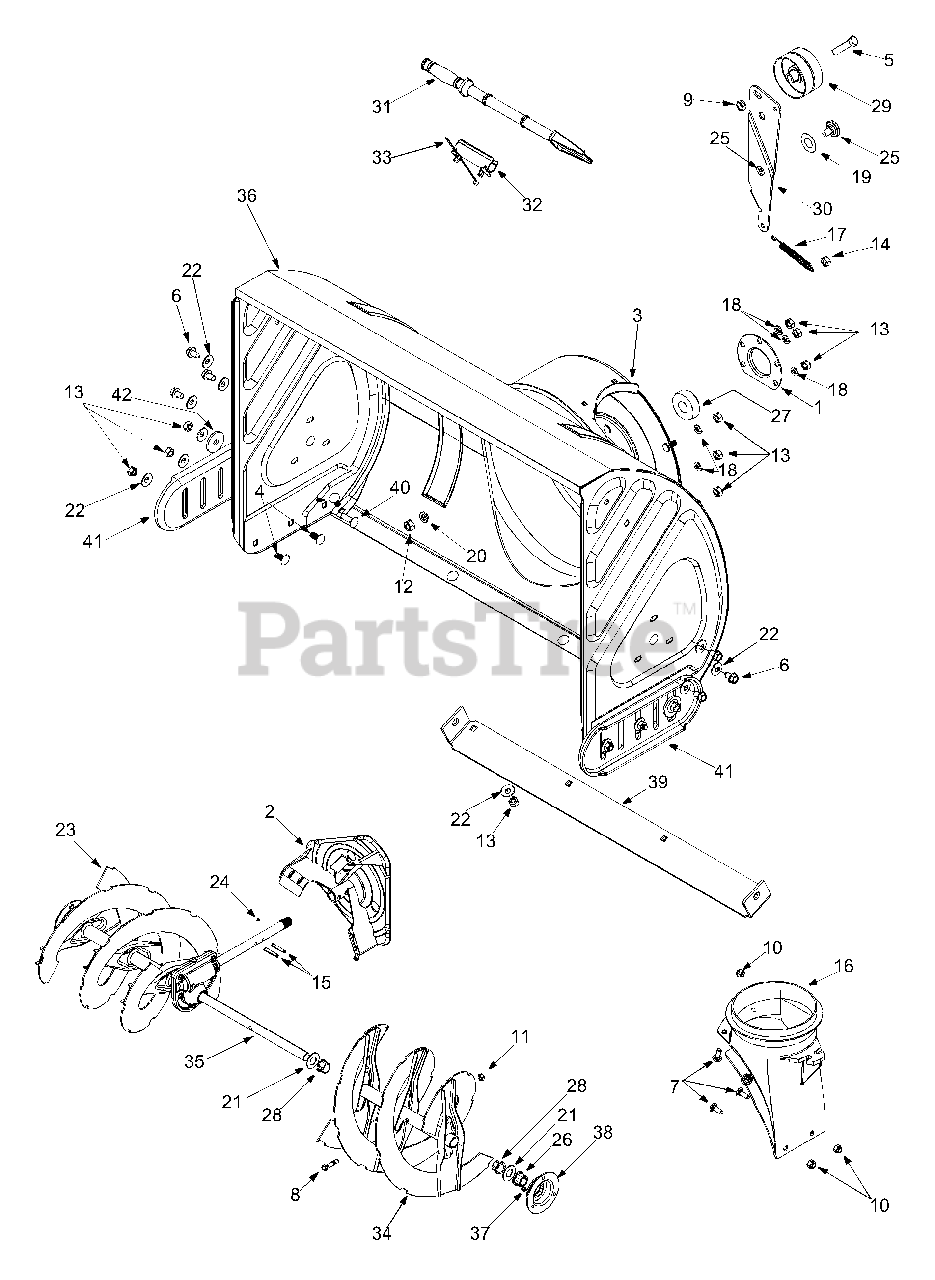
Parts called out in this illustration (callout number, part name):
1	Bearing Housing
4	Carriage Bolt
5	Hex Bolt 3/8-24 x 1.5"
6	TT Screw 5/16-12 x 0.75"
7	Carriage Screw 1/4-20 x 0.75"
8	Shear Bolt
9	Lock Nut 3/8-24
10	Hex Flange Lock Nut 1/4-20
12	Hex Nut 3/8-16
13	Hex Nut 5/16-18
14	Hex Lock Nut
15	Spring Pin
16	Chute Adapter
17	Extension Spring
18	Lock Washer
19	Flat Washer
20	Lock Washer
21	Flat Washer
22	Bell Washer
24	Grease
25	Shoulder Screw
26	Hex Flange Bearing
27	Ball Bearing
28	Flange Bearing
29	Flat Idler
31	Chute Clean-Out Tool
32	Tool Mount
33	Cable Tie
38	Bearing Housing
40	Carriage Screw 5/16-18 x 1.0"
42	Flat Washer.38 x 1.38 x.125
